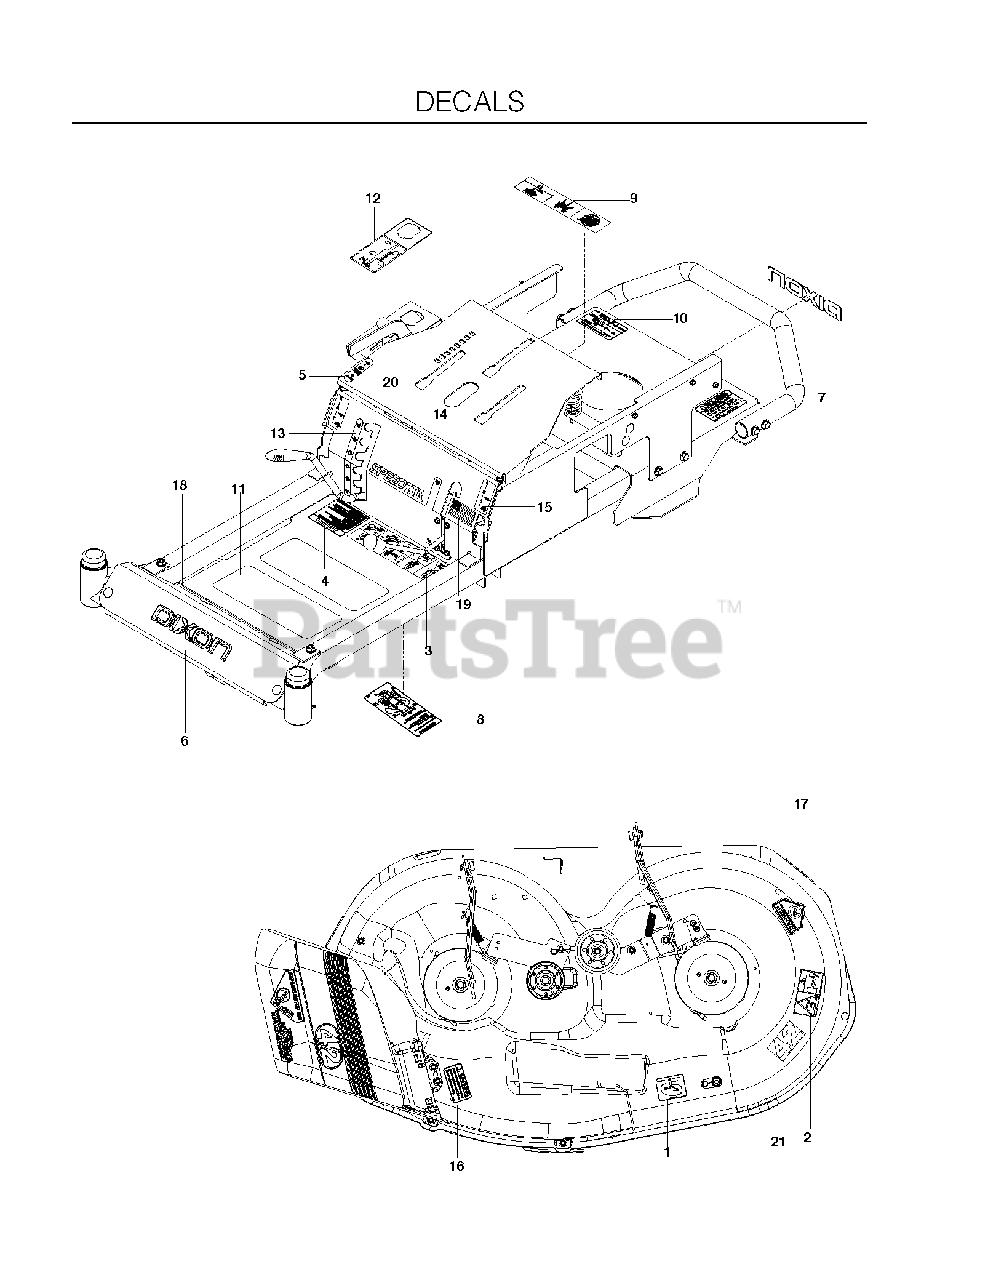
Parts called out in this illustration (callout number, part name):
1	DECAL, BELT ROUTING
2	DECAL, EURO SEVERING
3	DECAL, SAFETY WARNING
4	DECAL, WARNING
5	DECAL, PARK BRAKE
6	DECAL, DIXON LOGO, DOMED
7	DECAL, PROP. 65
8	DECAL, SERVICE
9	DECAL, BATTERY
10	DECAL, DO NOT MOUNT
11	ANTI-SKID PAD
12	DECAL, CONTROL PANEL
13	DECAL, DECK HEIGHT
14	DECAL, BLADE ENGAGEMENT
15	DECAL, MOTION CONTROL
16	DECAL, CAUTION
17	DECAL, CPSC
18	FOOT PAD
19	DECAL, FLAG
20	DECAL, SPEEDZTR 6.5"
21	DECAL, DECK 42"
